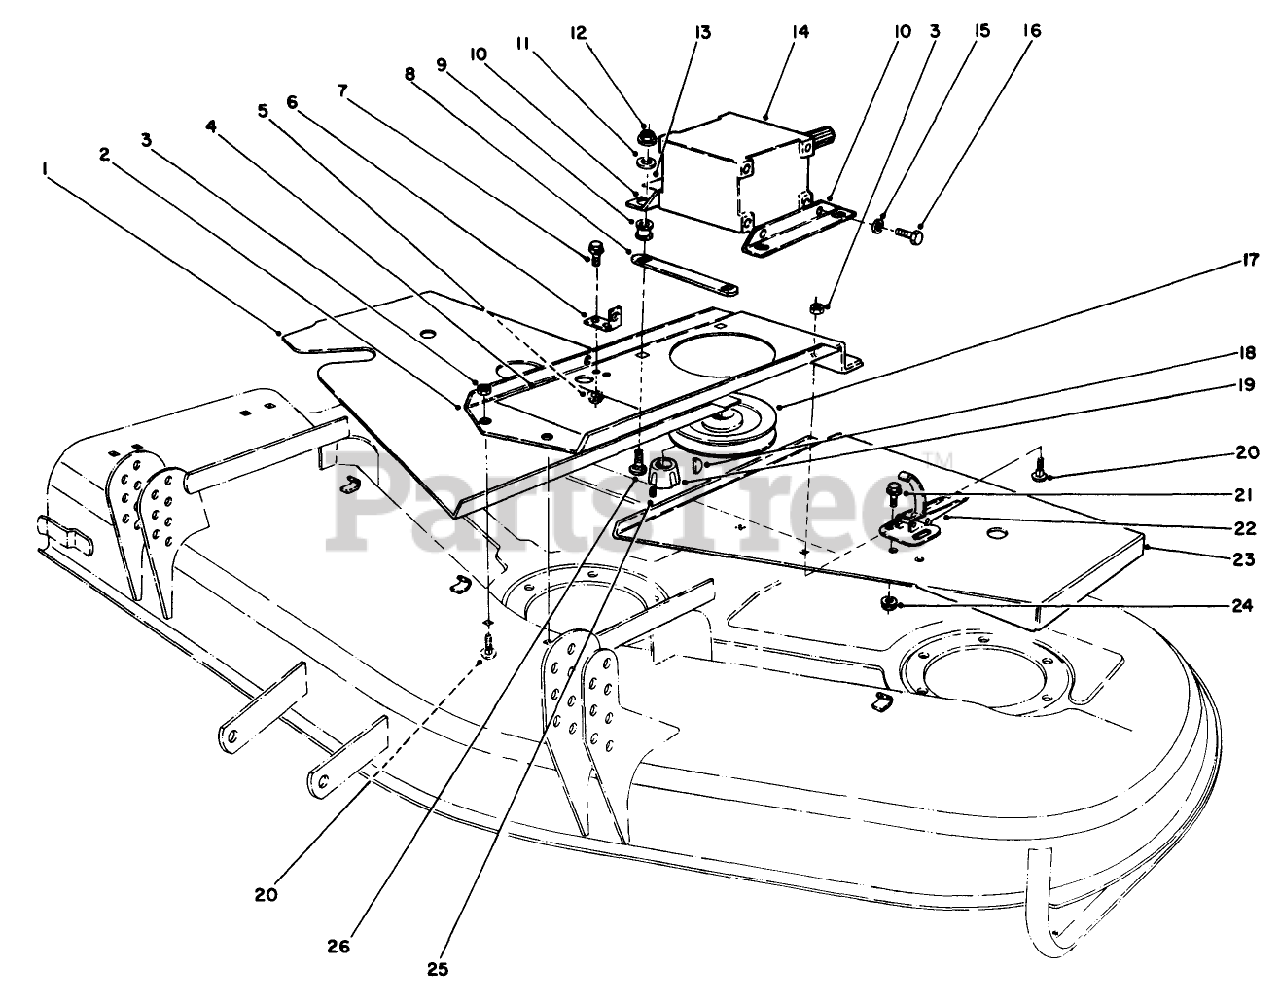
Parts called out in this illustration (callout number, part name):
1	Cover R.H
2	Base-Gear Box
3	NUT-HHF, WHIZ
4	DECAL
5	NUT-HF
6	Bracket-Extension
6	FITTING-GREASE, 90 DEG
7	SCREW-HH
8	Cover-Gear Box
9	MOUNT
10	Bracket-Gearbox
11	WASHER
12	NUT-LOCK, SIDE
13	DECAL-OIL
14	Gearbox
15	WASHER-LOCK
16	SCREW-HH
17	PULLEY
18	KEY-WOODRUFF
19	Bushing-Taper Lock (Incl. Ref. #25)
20	SCREW-CARR
21	SCREW-HWH
22	CLAMP-SLOTTED
23	Cover LH
24	Nut-Flange
25	SCREW-SET, HSH
26	SCREW-CARR
